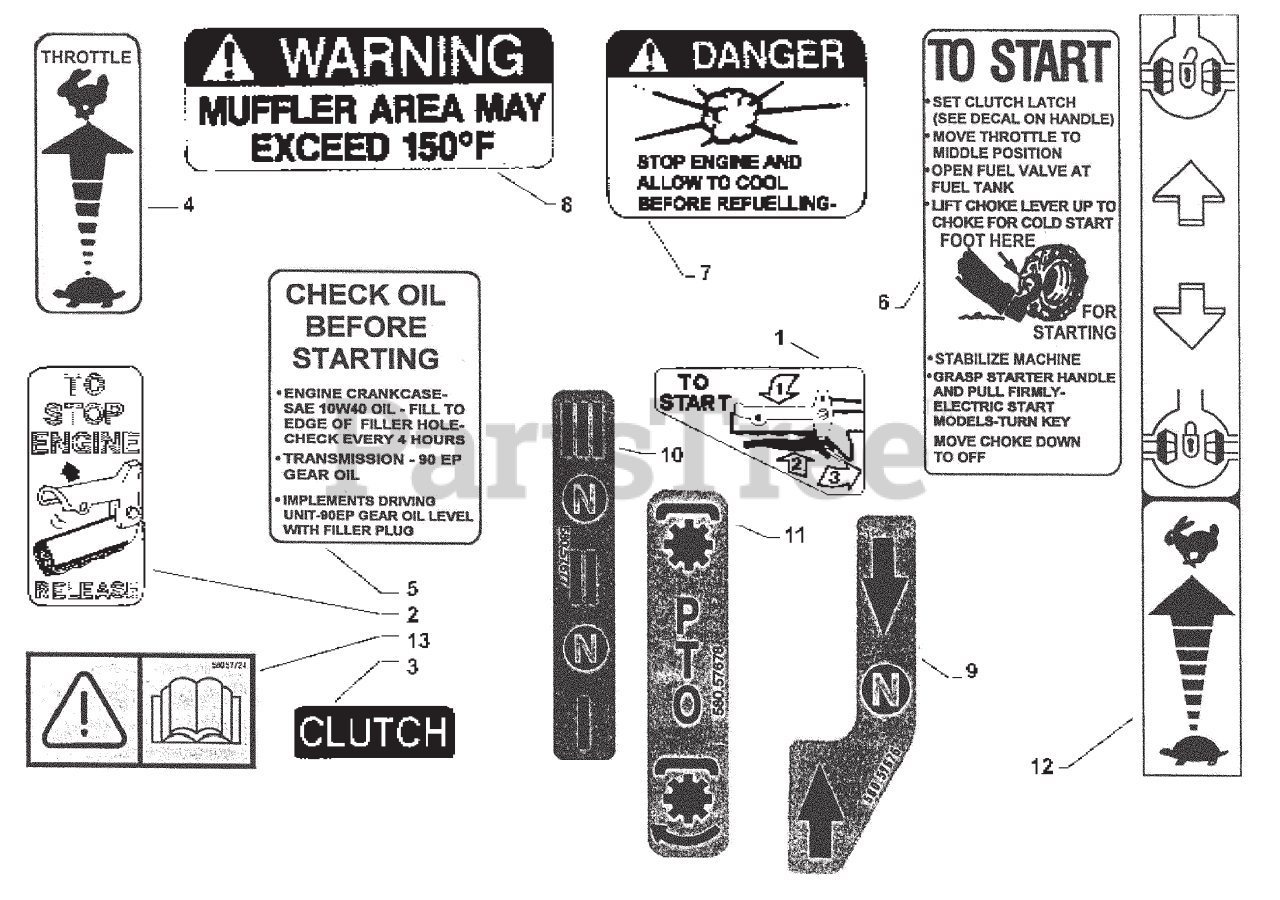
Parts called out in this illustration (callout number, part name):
1	DECAL, TO START
2	DECAL, ENGINE STOP
3	DECAL, CLUTCH
4	DECAL, THROTTLE
5	DECAL, CHECK OIL
6	DECAL, TO START
7	DECAL, DANGER
8	DECAL, WARNING
9	DECAL, NEUTRAL
10	DECAL, GEAR
11	DECAL, PTO
12	DECAL, DIFF & THROTTLE
13	DECAL, READ OP MANUAL
